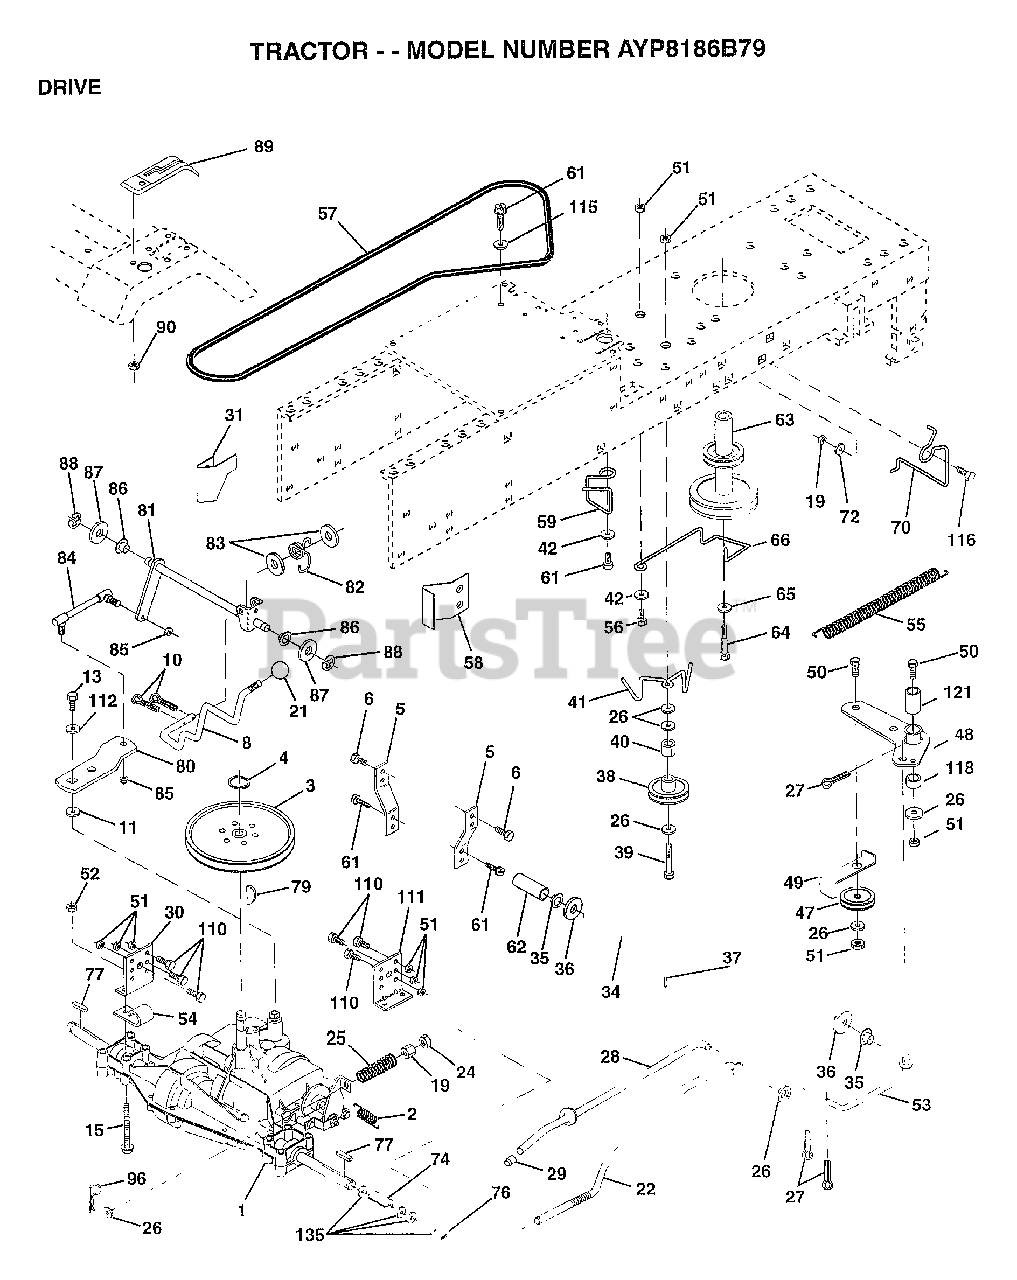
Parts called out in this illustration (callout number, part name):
3	PULLEY TRANSAXLE
5	STRAP TORQUE
6	SCREW
8	ROD SHIFT FEND YT
10	PIN COTTER 1/8
11	WASH-SHFT PLT LT
13	BOLT.1/4-28.W/PAT
19	NUT
21	KNOB T (1/2-HOLE)
22	ROD.ASM.BK.44.MWR
24	NUT
25	"SPRING,ROD BRAKE"
26	WASHER
27	COTTER PIN
28	ROD.BRAKE.PARK.LT
30	BRKT TRANS LH
31	KEEPER BELT LH
34	SHAFT ASM-PEDAL F
35	NYLON BEARING
36	WASHER LT
38	PULLEY.IDLER.FLAT
39	BOLT
40	SPACER T
42	WASHER
48	BELLCRANK ASM
49	RETAIN BELT
53	"LINK, CLUTCH T"
54	"CLIP,INSULATOR"
55	"SPRING, RETURN LT"
57	BELT.GRDRV.94.75
58	"KEEPER,BELT RH"
59	KEEPER BELT CNTSP
61	SCREW
62	PEDAL COVER T
64	BOLT
65	LOCKWASHER
66	KEEPER-BELT
70	"GUIDE.BELT,RH ENG"
72	WASHER
74	SPACER HYT
76	E RING HYT
77	SQ KEY STD
80	"ARM,SHIFT"
81	"SHAFT,SHIFTER"
82	"SPRING,TORSION"
83	WASHER
84	"ROD LINK,SHIFT AD"
85	NUT.CNT.LOCK.1/4
86	BUSHING
87	WASHER D
88	KLIP RING
89	CONSOLE SHIFTER
90	NUT
96	RETAINER M
100	WASHER M
102	WASHER BELLEVILLE
111	BRKT TRANS RH
112	WASHER PM
115	WASHER GT
116	BOLT RDHD 3/8-16
118	SPACER-BELLCRANK
121	NYLINER-CLUTCHING
135	WASHER
137	WASHER
138	WASHER
139	BOLT
